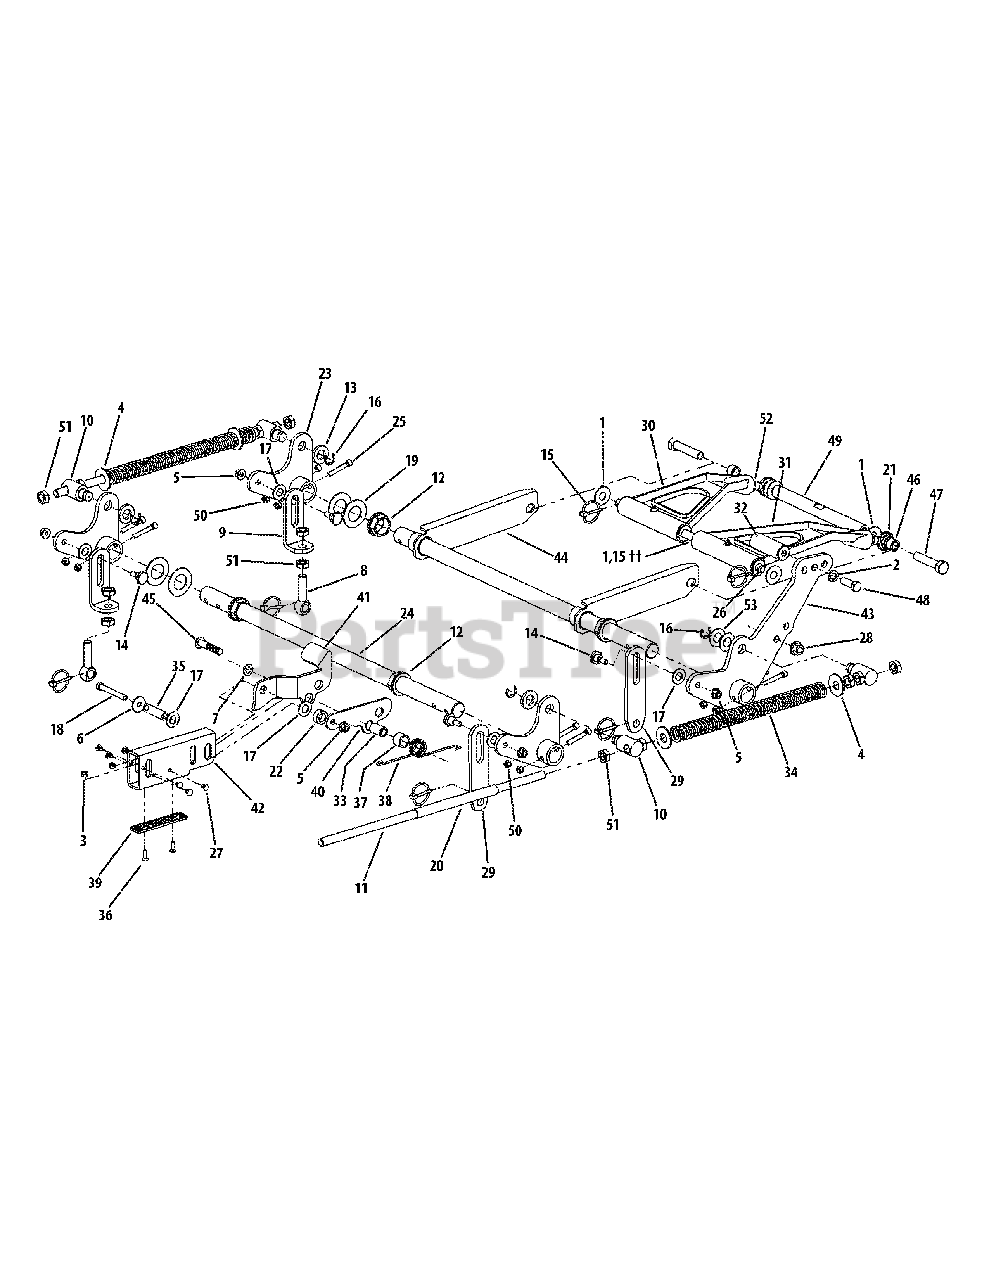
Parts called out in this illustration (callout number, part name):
1	Washer, 1.5 x .655 x .055
2	Lock Washer, 1/2
3	Lock Nut w/Nylon Insert
4	Flat Washer, 5/8
5	Hex Nut, Flange Lock, 3/8-16
6	Flat Washer, 1.25 x .411 x .100
7	Flat Washer, .536 ID x .930 OD x .05
8	Eye Bolt, 5/8ID
9	Eye Bolt Mount Link, 5/8 ID
10	Ferule Lift
11	Lift Connector Rod
12	Hex Flange Bearing, 1.25 ID
13	Spacer, .812 ID x .268 Lg.
14	Shoulder Screw, 0.625 OD x .437 Lg.
15	Linch Pin, 3/16 Dia.
16	E Clip, 3/4 Dia.
17	Nylon Flat Washer, 5/8
18	HHCS, 3/8-16, 3.00
19	Flat Washer, 1.25 ID
20	Hose, 5/8 ID 13/16 OD, 8" LG
21	Rod End, Male
22	Spacer, .630 ID x 1.06 OD x .440
23	Bellecrank Weldment Assembly
24	Deck Lift Shaft
25	Socket Head Cap Screw, 5/16-18 x 2
26	Lift Link Rod
26	Lift Link Rod 72"
27	Rivet, 1/4 x 5/8
28	Nut, 1/2-13, Flange Lock
30	Bearing Lift Brace Ass’y, LH incl.:
30	Grease Fitting
31	Bearing Lift Brace Ass’y, RH incl.:
31	Grease Fitting
32	Deck Lift Foot Pedal
33	Spacer, .51 ID x .75 OD x 1.240
34	Lift Compression Spring
35	Spacer, .375 ID x .625 OD x 2.20
36	Flat Head Cap Screw, 1/4-20 x .75
37	Spacer, .76 ID x 1.0 OD x .75
38	Torsion Spring, .120 Wire x 1.32 OD
39	Lift Wear Plate
41	Lift Link Bracket
42	Lift Tube, 3.0 x 1.5
43	Deck Lift Foot Pedal Weldment
44	Front Frame Strut Assembly
45	Cap Screw, 1/2-13 x 2.50
46	Spacer, .632 x .877 x .548
47	HHCS, 5/8-11 x 3.00
48	Hex Cap Screw, 1/2-13 x 1.50
49	Front Lift Link Shaft, Threaded
50	Nut, 5/16-18, Nylock
51	Jam Nut, 5/8-11
52	Jam Nut, 5/8-18
53	Flat Washer, .76 x 1.49 x .06
